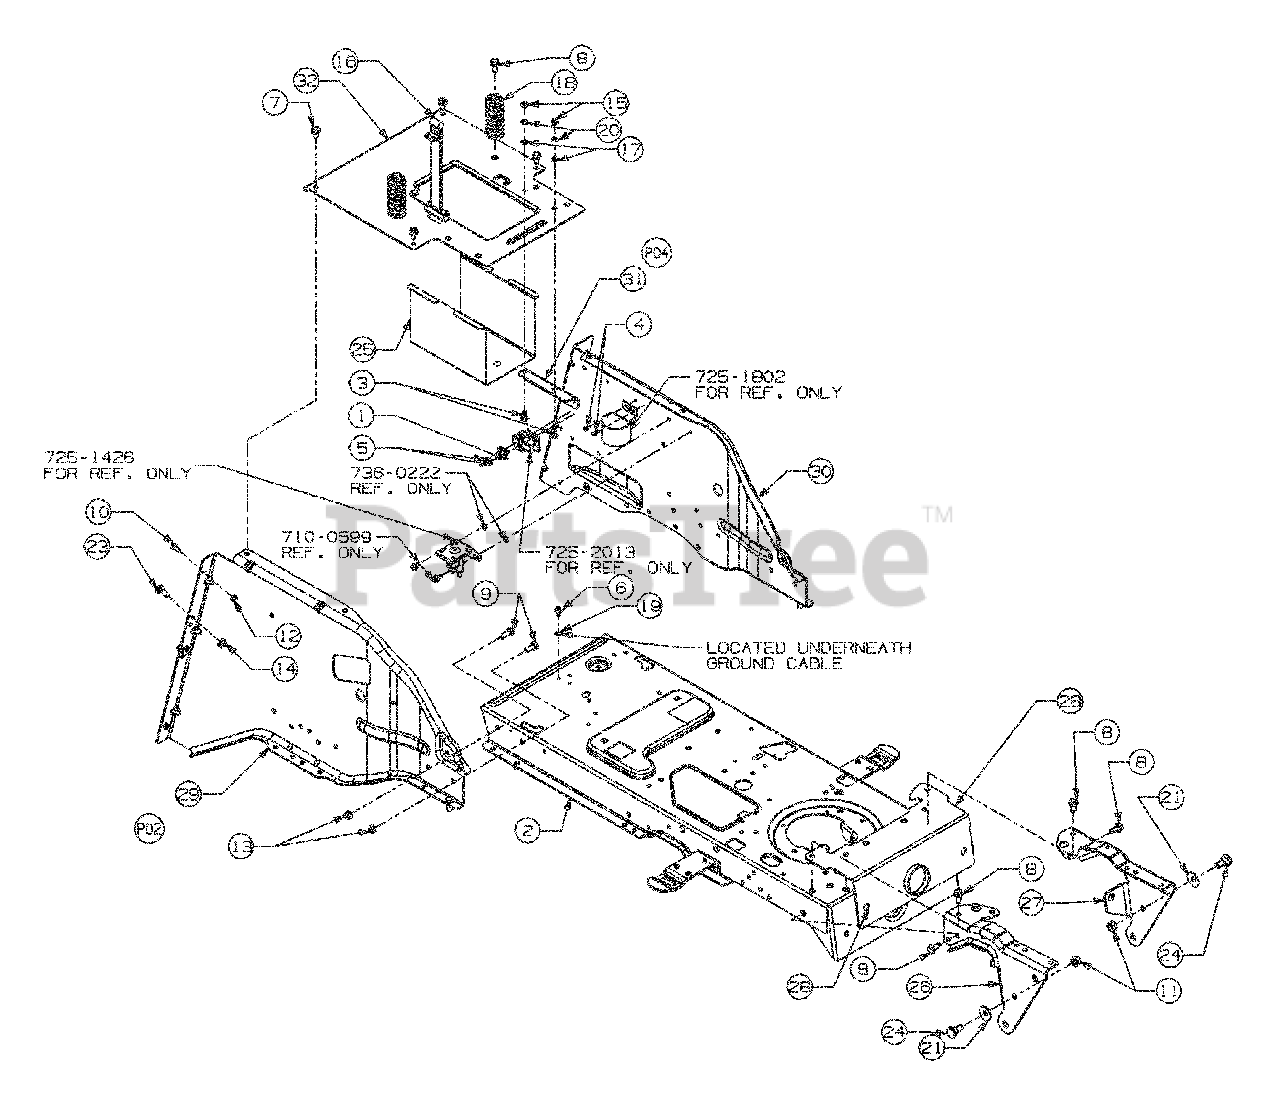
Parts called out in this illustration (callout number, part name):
3	SCR:CRG:1/4-20:.62:GR2
4	SCR:F:#8-32:0.375:HXINDWSH
5	SCR:AB:#10-16:0.500:HXINDWSH
6	SCR:TT:1/4-20:0.500:HXINDWSH
7	SCR:TT:5/16-18:0.625:HXINDWSH
8	SCR:LD:5/16-18:0.750:HXINDWSH
9	HHCS:M8-1.25:20.00:GR8.8:STD
10	SCR:M6-1:12.00 LG DIN 933
11	NUT:FLGLK:3/8-16:GRF:TOP LK
12	NUT:HEXLK:M6-1:NYLON DIN 985
13	NUT:HEXLK:M8-1.25:NYLON DIN985
14	NUT:FLGLK:5/16-18:GR5:SD LK
15	NUT:HEX:1/4-20:GR5
16	STRAP:BAT:400
17	NUT:PUSH:.25 ID X .50 OD
18	SPR:COMPRS:1.28 OD X 3.125
19	EXTERN L-WASH 1/4
20	WASH:LOCK:1/4:REGULAR DUTY
21	WASH:BELL:.390 X 1.13 X .062
23	SCR:SHLD:.435 X .178-5/16 X .56
30	FRM:RR:LH HYDRO 500
